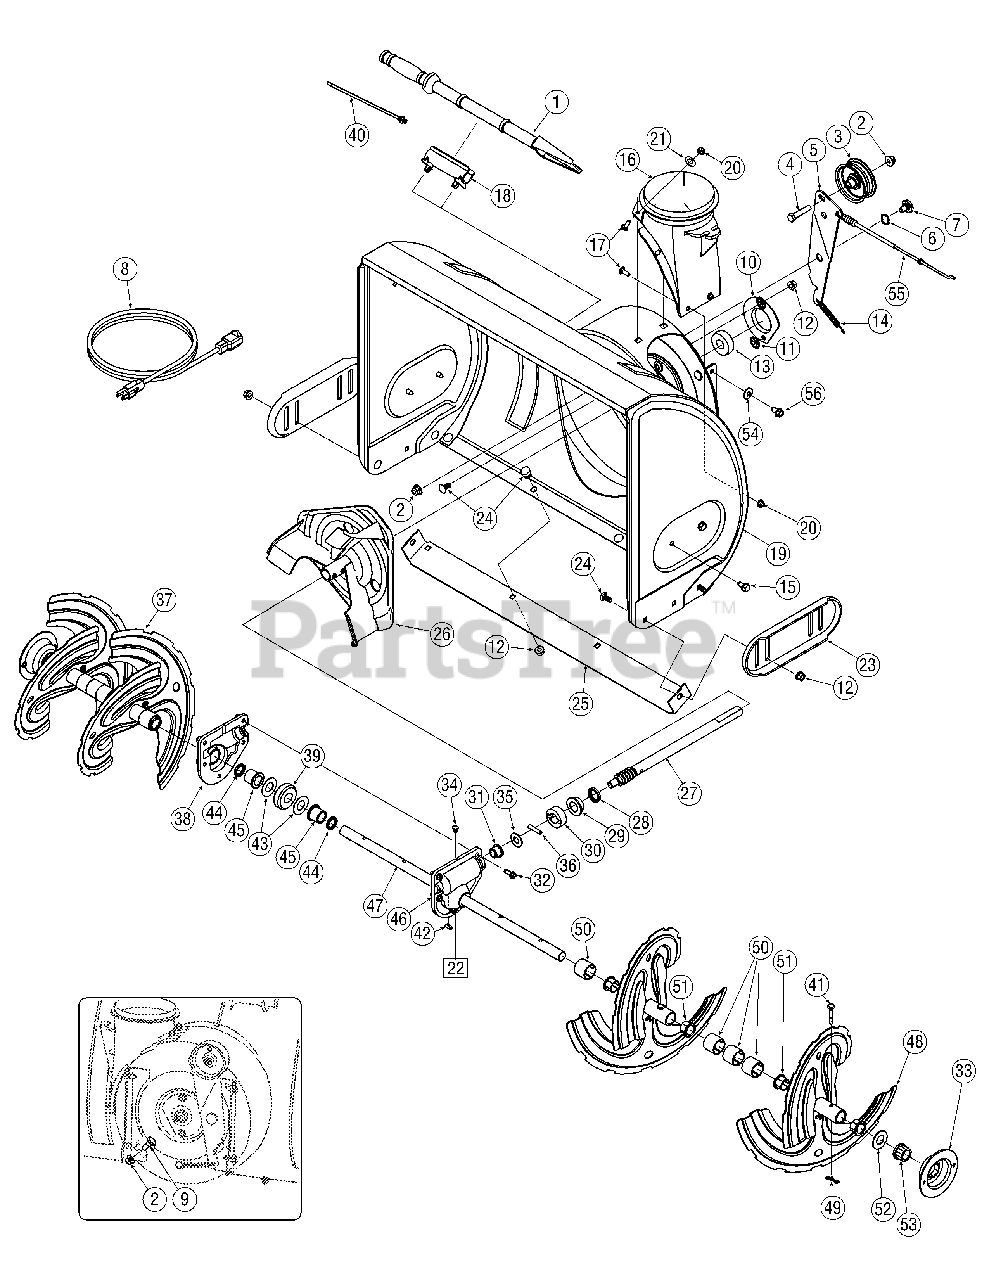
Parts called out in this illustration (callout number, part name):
1	Clean-Out Tool
2	Flange Lock Nut
3	Flat Idler Pulley
4	Hex Bolt, 3/8-16 x 1.75
6	Wave Washer
7	Shoulder Screw
8	Extension Cord
9	Shoulder Screw
10	Bearing Housing
11	Push Nut
12	Flange Lock Nut, 5/16-18
13	Ball Bearing
14	Extension Spring
15	Screw, 5/16-18 x 0.625
16	Chute Adapter
17	Carriage Screw, 1/4-20 x 0.75
18	Clean-out Tool Mtg. Bracket
20	Flange Lock Nut, 1/4-20
21	Flat Washer
22	Gearbox Assembly Complete
24	Carriage Bolt
27	Worm Shaft
28	Oil Seal
29	Flange Bearing
30	Thrust Collar
31	Flange Bearing
32	TT Screw, 1/4-20 x 0.75
35	Flat Washer
36	Dowel Pin
38	Reducer Hsg.-RH (Incl Ref. 44-45)
39	Worm Gear, 20T
40	Cable Tie
41	Shear Pin
42	Key
43	Flat Washer
44	Oil Seal
45	Flange Bearing
46	Reducer Hsg.-LH (Incl Ref. 44-45)
47	Auger Axle
49	Bow Tie Cotter Pin
50	Spacer
51	Flange Bushing
52	Flat Washer
53	Hex Flange Bearing
54	Bell Washer
55	Auger Clutch Cable
56	Screw, 5/16-18 x 0.75
